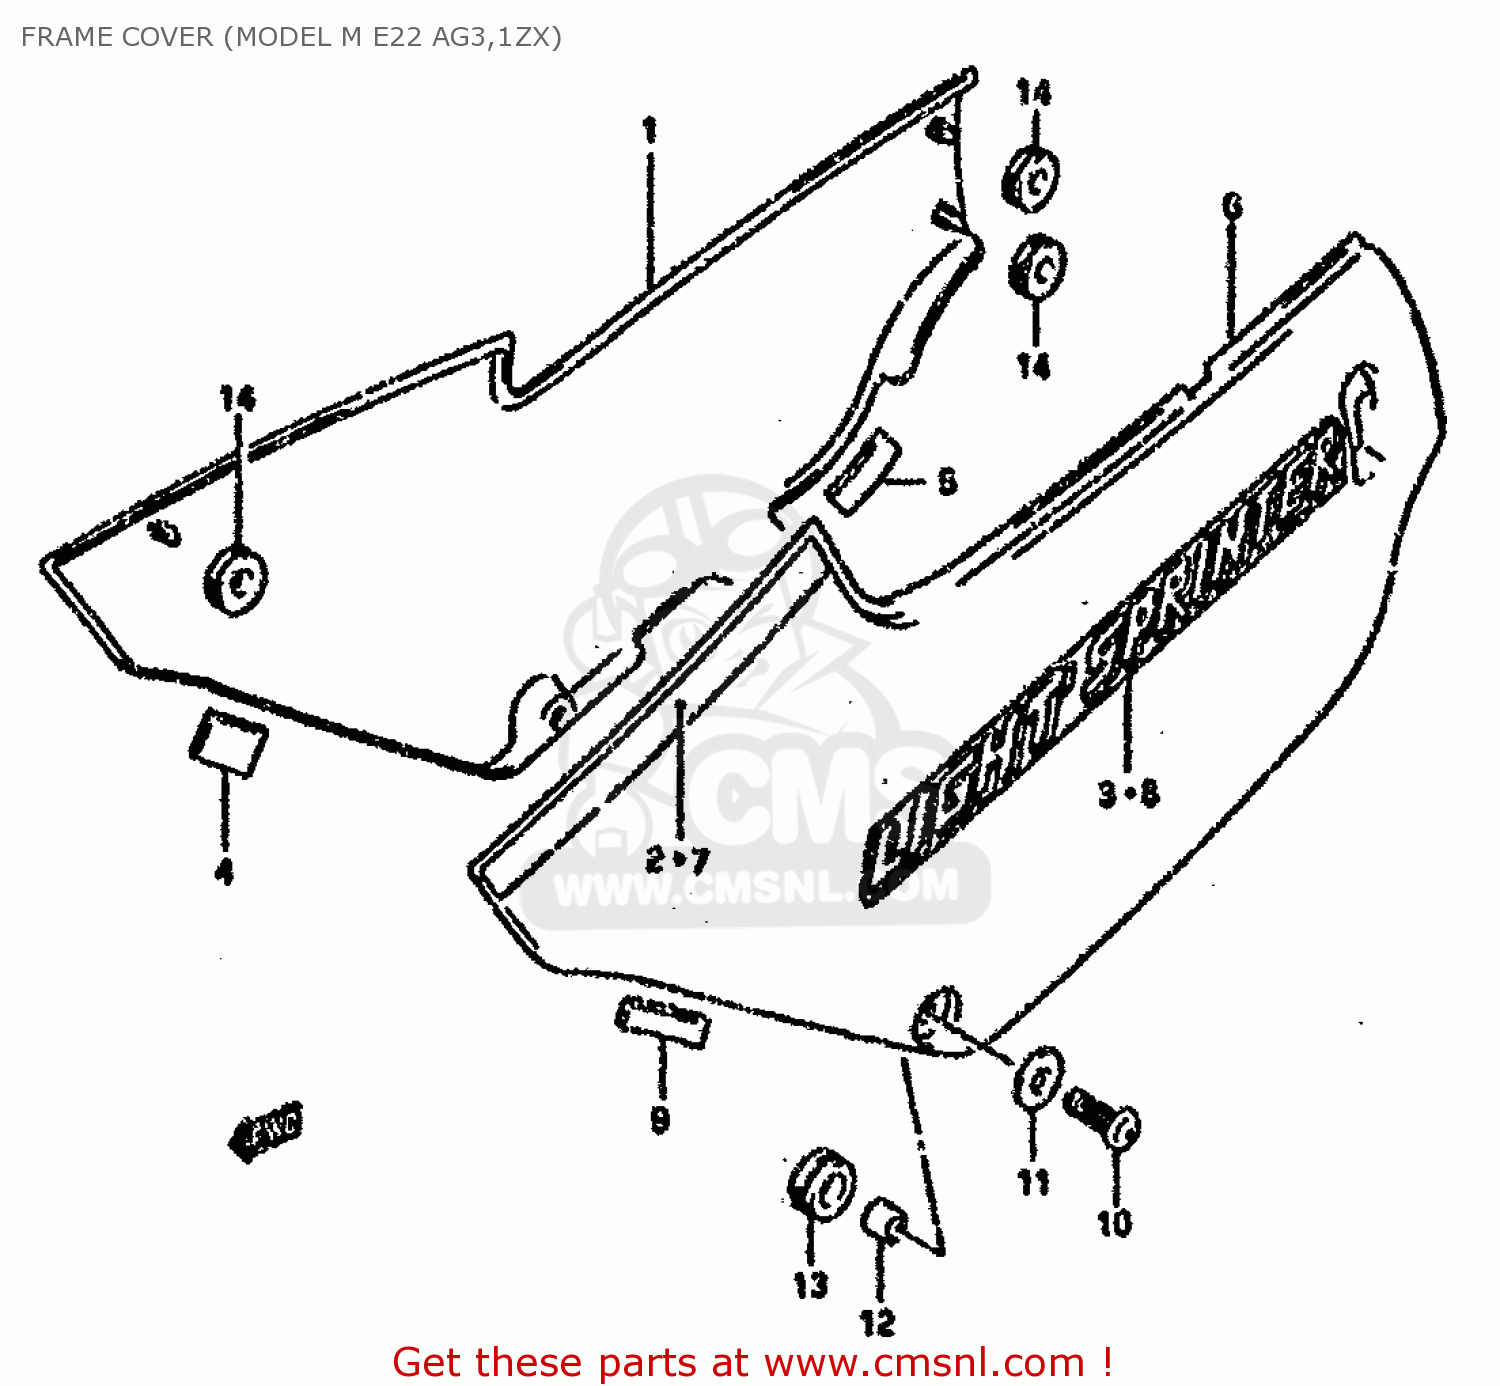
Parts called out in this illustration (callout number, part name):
1	COVER,FRAME RH (GRAY)
2	TAPE,FRAME COVER RH
3	EMBLEM
4	CUSHION, FRONT RH
5	CUSHION, REAR RH
6	COVER,FRAME LH (GRAY)
7	TAPE,FRAME COVER LH
8	EMBLEM
9	CUSHION, LH
10	SCREW
11	WASHER(6.5X18X1)
12	SPACER (6.1X9X9)
13	CUSHION
14	CUSHION
17	CUSHION
18	CUSHION
21	WASHER(6.5X18X1)
22	SPACER (6.1X9X9)
23	CUSHION
24	CUSHION
